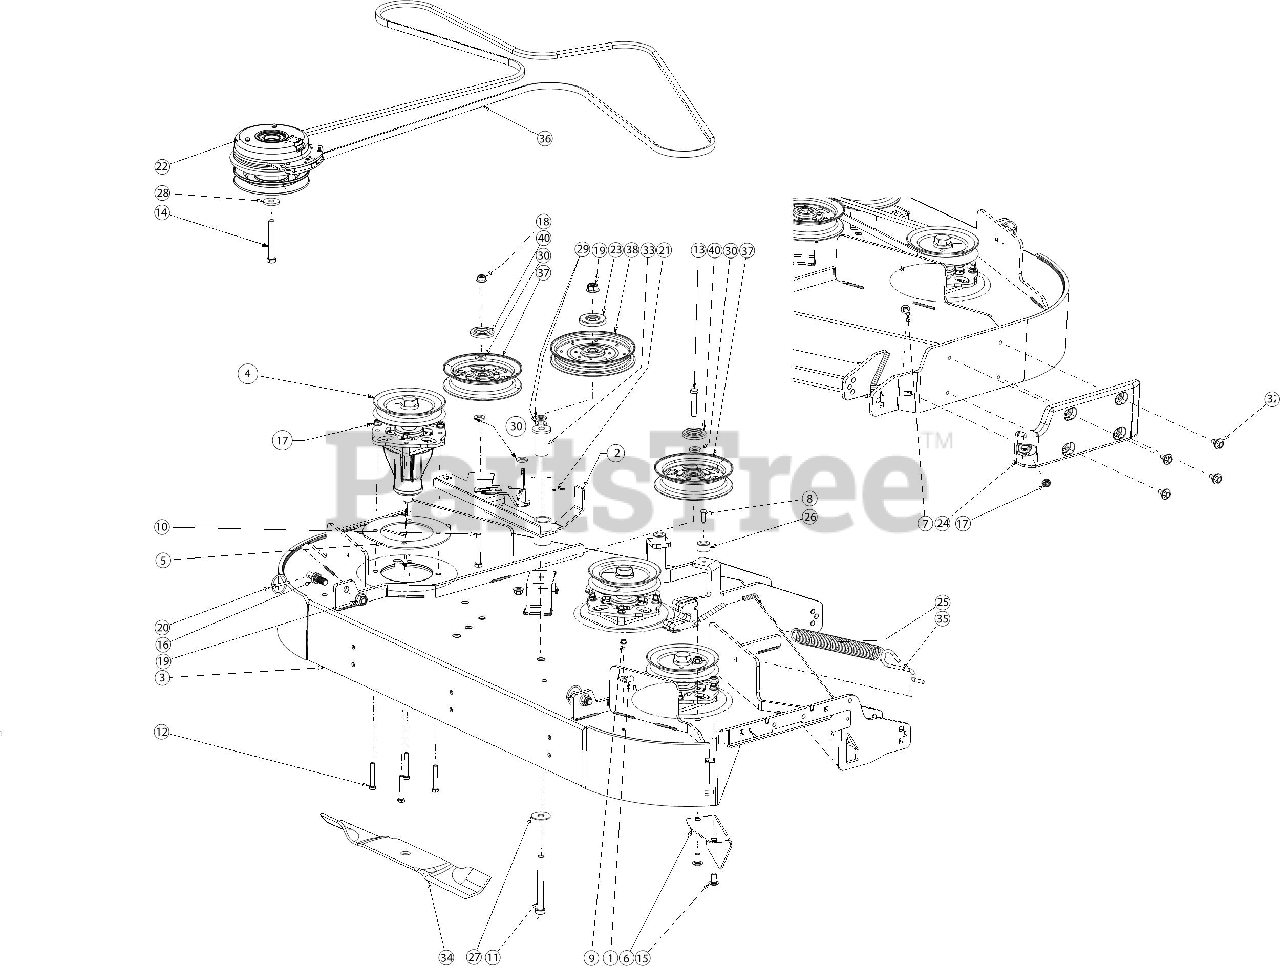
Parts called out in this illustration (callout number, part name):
1	HOOK RETAINING BRACKET
2	DECK IDLER ASSEMBLY
3	DECK ASSEMBLY
4	V-PULLEY 5.768 DIA
5	SPINDLE REINFORCEMENT PLATE
6	DECK CHUTE BAFFLE
7	CARRIAGE BOLT 5/16-18 X 1.00
8	SCREW 1/4-20 X 1.0
9	SCREW 1/4-20 X.500
10	HEX SCREW-3/8-16X2.5 GR5
11	SCREW 1/2-13 X 4.5 GR 5
12	SCREW 5/16-18 X 2.0 GR5
13	SCREW 3/8-16 X 2.0 GR5
14	SCREW 7/16-20 x 3.25 GR5
15	CARRIAGE BOLT 3/8-16 X .75
17	FLANGE LOCK NUT 5/16-18
21	COTTER PIN 3/32
22	ELECTRIC PTO CLUTCH
23	PULLEY CAP 1/2",1"
24	DECK SKID PLATE (LH)
25	EXTENSION SPRING
27	WASHER .51 X 1.5 X .07
28	FLAT WASHER .445 X 1.248 X .170
29	FLAT WASHER
30	FLAT WASHER
32	SHOULDER SCREW .43X.29X5/16-18 TT
33	SHOULDER SPACER 1.050 X .503 X 2.157
34	19 BLADE (HI LIFT)"
35	DECK SPRING HOOK
36	V-BELT B SEC X 154
37	IDLER PULLEY 5.0
38	IDLER PULLEY 6.0 DIA"
40	IDLER PULLEY CAP
